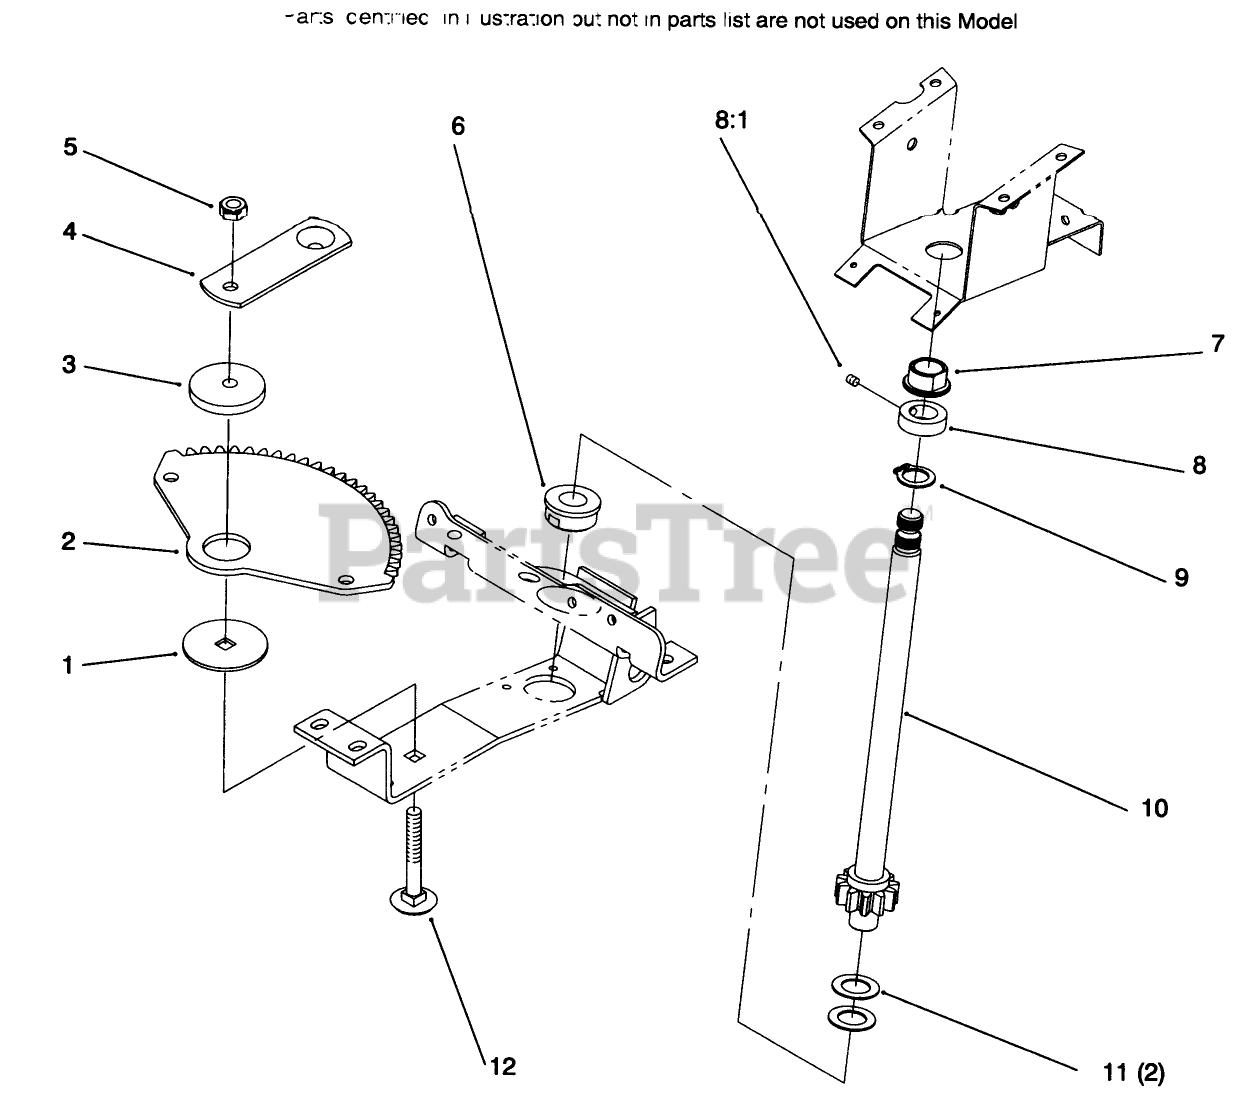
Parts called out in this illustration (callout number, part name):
1	WASHER-BEARING
3	BUSHING
5	NUT-HEX
6	BEARING-WHEEL
7	BEARING-FLANGED
8	COLLAR
8:1	SCREW-HSH
9	RING-RETAINING
10	SHAFT-STEERING, LOWER
11	WASHER
12	SCREW-CARR
